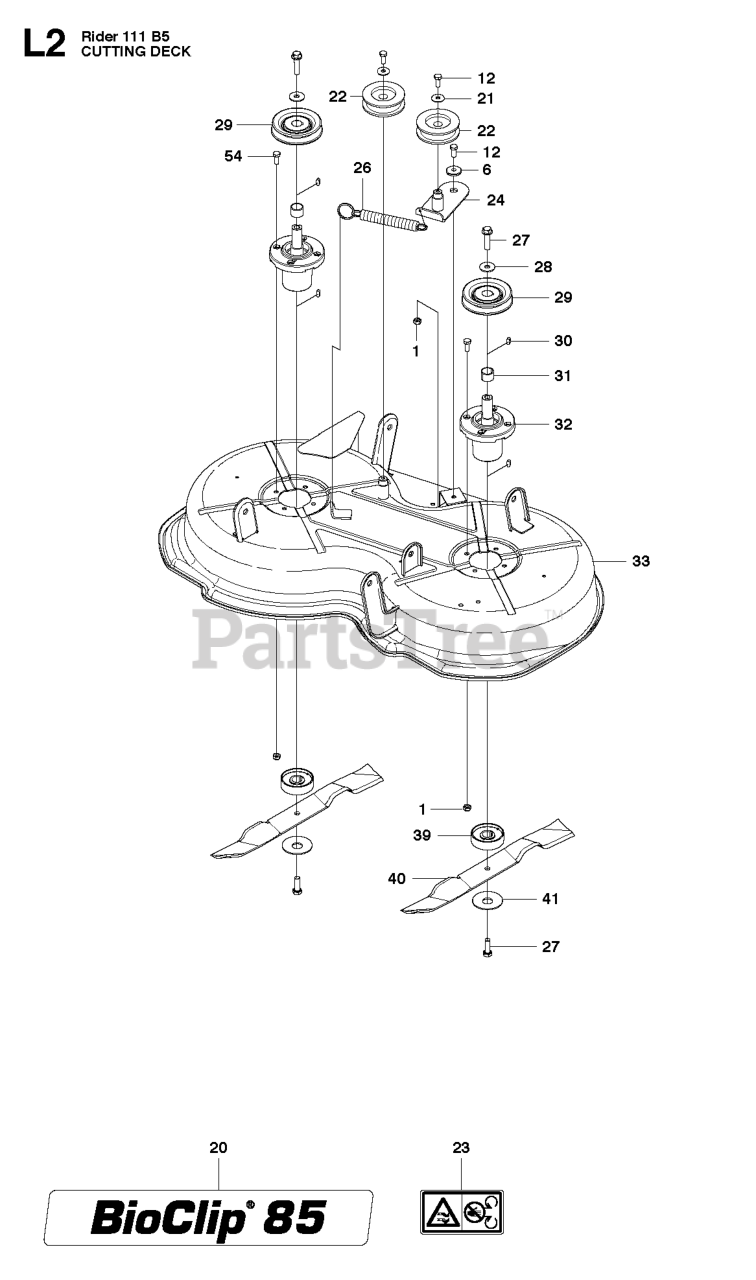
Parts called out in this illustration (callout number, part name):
1	LOCKNUT M8
6	WASHER
22	PULLEY
32	BEARING HOUSING ASSY
